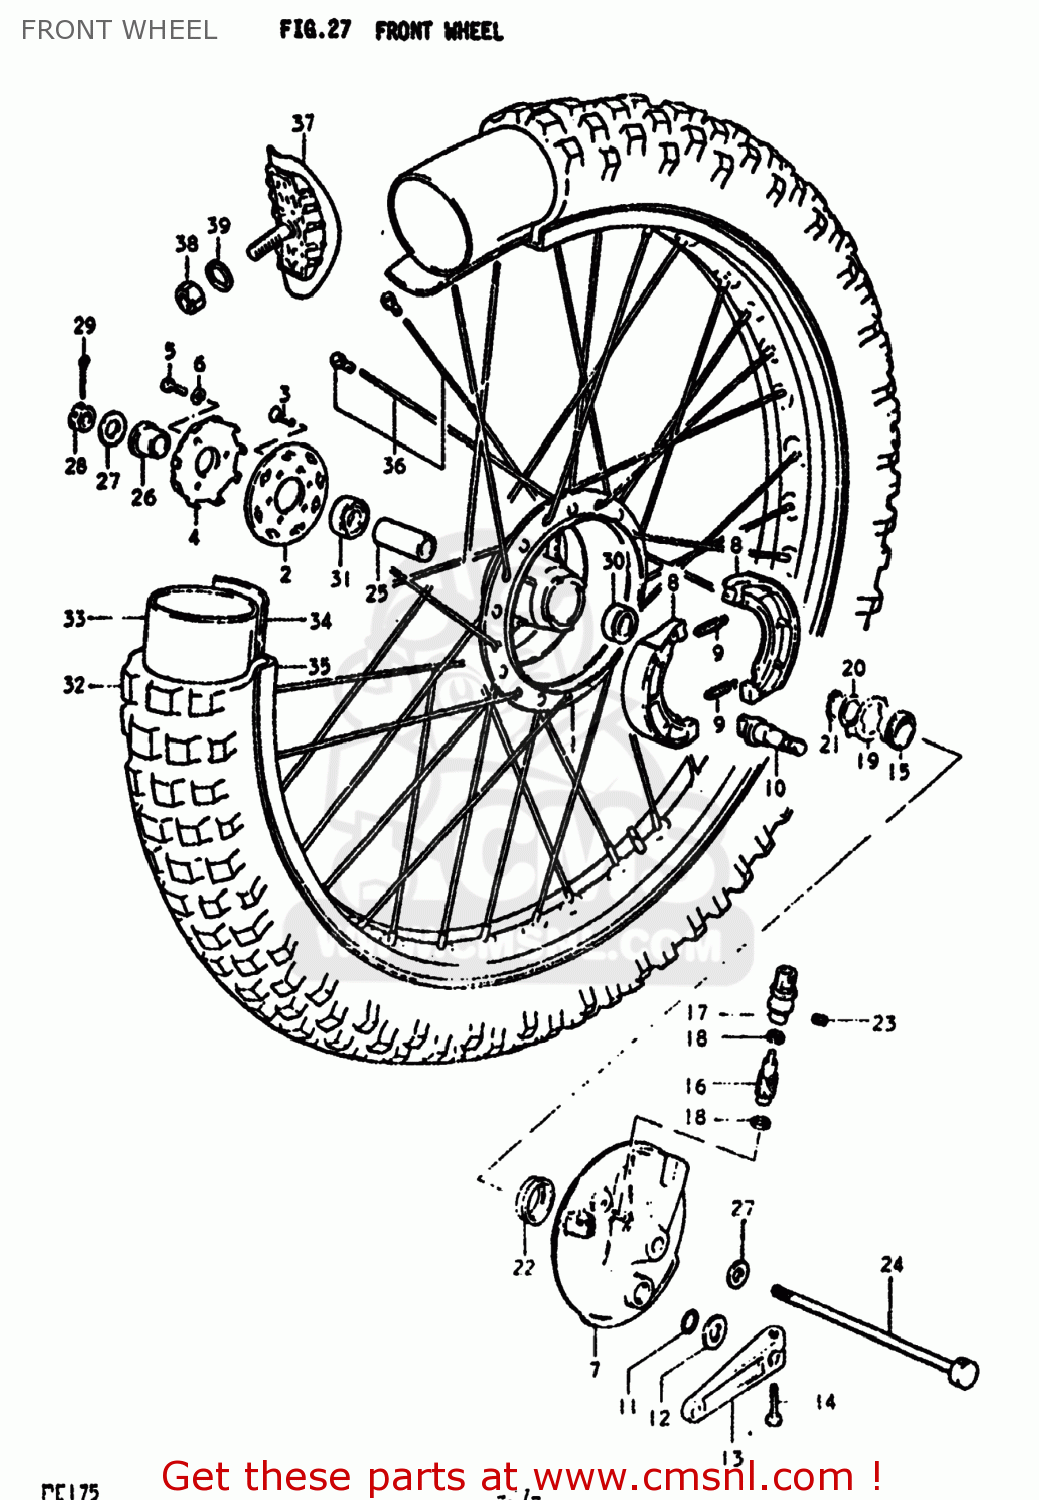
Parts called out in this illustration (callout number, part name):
1	HUB,FRONT
2	FLANGE,FRONT HUB,RIGHT
3	SCREW
4	RETAINER,FR HUB BEARING,R
5	BOLT, UPPER
6	LOCK WASHER
7	PANEL,FRONT HUB
8	SHOE,BRAKE
9	SPRING(L:34)
10	CAM,FRONT BRAKE
11	O RING(D:2.5,ID:11.4)
12	WASHER(12.5X20X1)
13	LEVER,FRONT BRAKE CAM
14	BOLT
15	GEAR,SPEEDOMETER
16	PINION,SPEEDOMETER
17	BUSH,METER GEAR OUTER
18	WASHER (5.1X9X0.4)
19	DRIVER,SPEEDOMETER GEAR
20	WASHER(18.5X24X1)
21	CIRCLIP
22	OIL SEAL (43X58X7)
23	SCREW
24	AXLE,FRONT
25	SPACER (12.6X19X52)
26	SPACER,FR AXLE,R
27	WASHER
28	NUT, REAR AXLE
29	COTTER PIN
30	BEARING
31	BEARING
32	TIRE,FRONT
33	TUBE
34	PROTECTOR,WHEEL,INNER
35	RIM,FRONT WHEEL
36	SPOKE SET,FRONT
37	STOPPER,BEAD
38	NUT
39	WASHER
